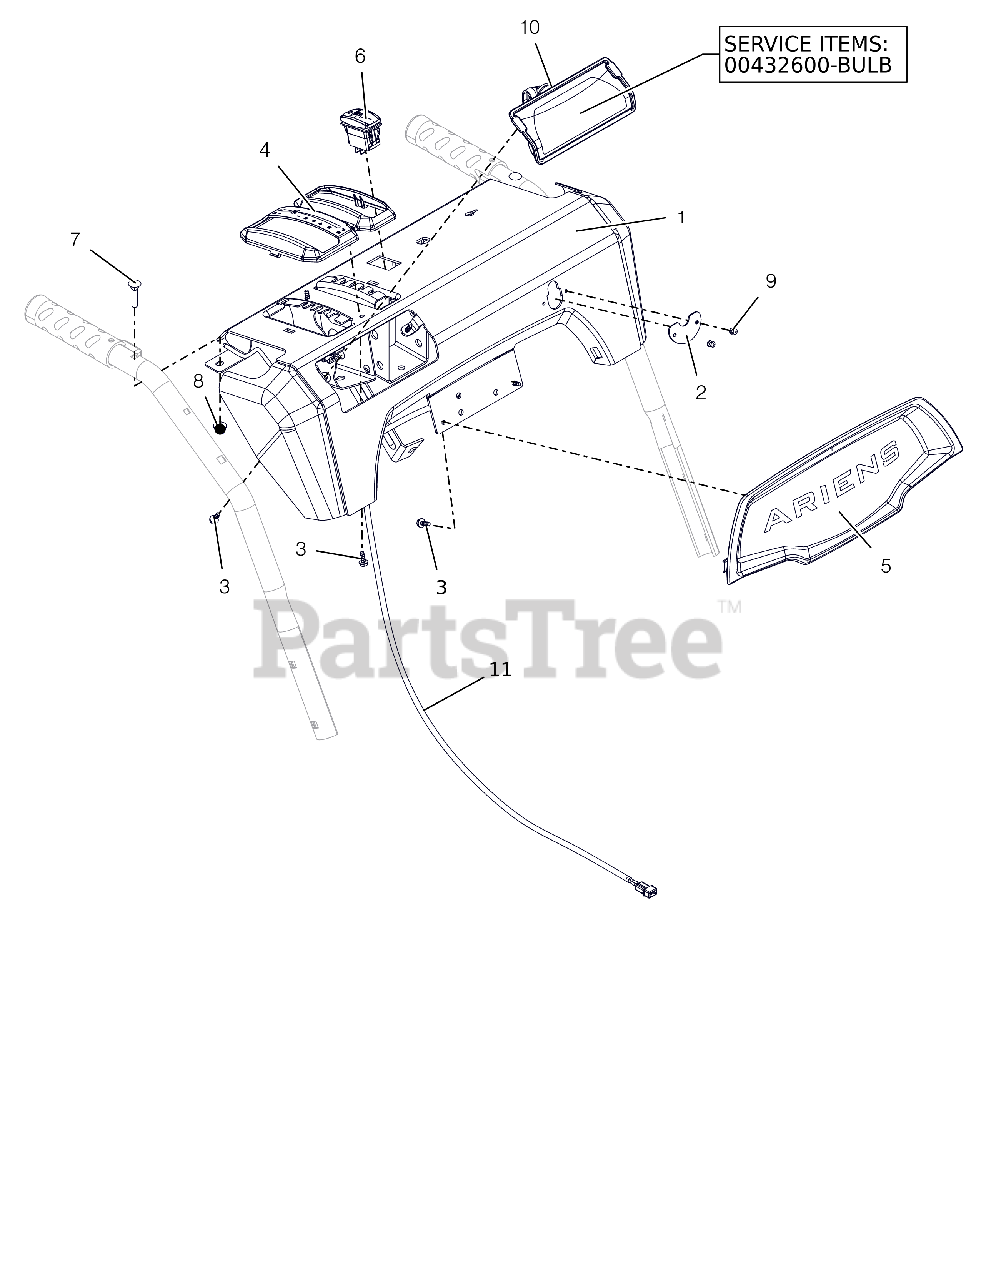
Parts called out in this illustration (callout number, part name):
1	CONTROL PANEL W/DECAL FRIC-ID
2	COVER, DASH BRKT, ID
3	SCR-TAP #10X.50 BOSS INDHXHD
4	BEZEL, SHIFT - FRICTION SNOW
5	BEZEL, DASH - ARIENS LG DASH
6	SWITCH,ROCKER SPST-ON/OFF
7	BLT-RDHDXLSQNK.25-20X1.25 G5ZC
8	@NUT-LK-CTR-FLG .25-20 YWZC
9	RVT-POP #43 .125X.313 STL ZINC
10	HEADLIGHT ASY, HALO 20W 2SHOT
10	BULB, LIGHT-HALOGEN 20W
11	HARNESS, LIGHT & WARMER
